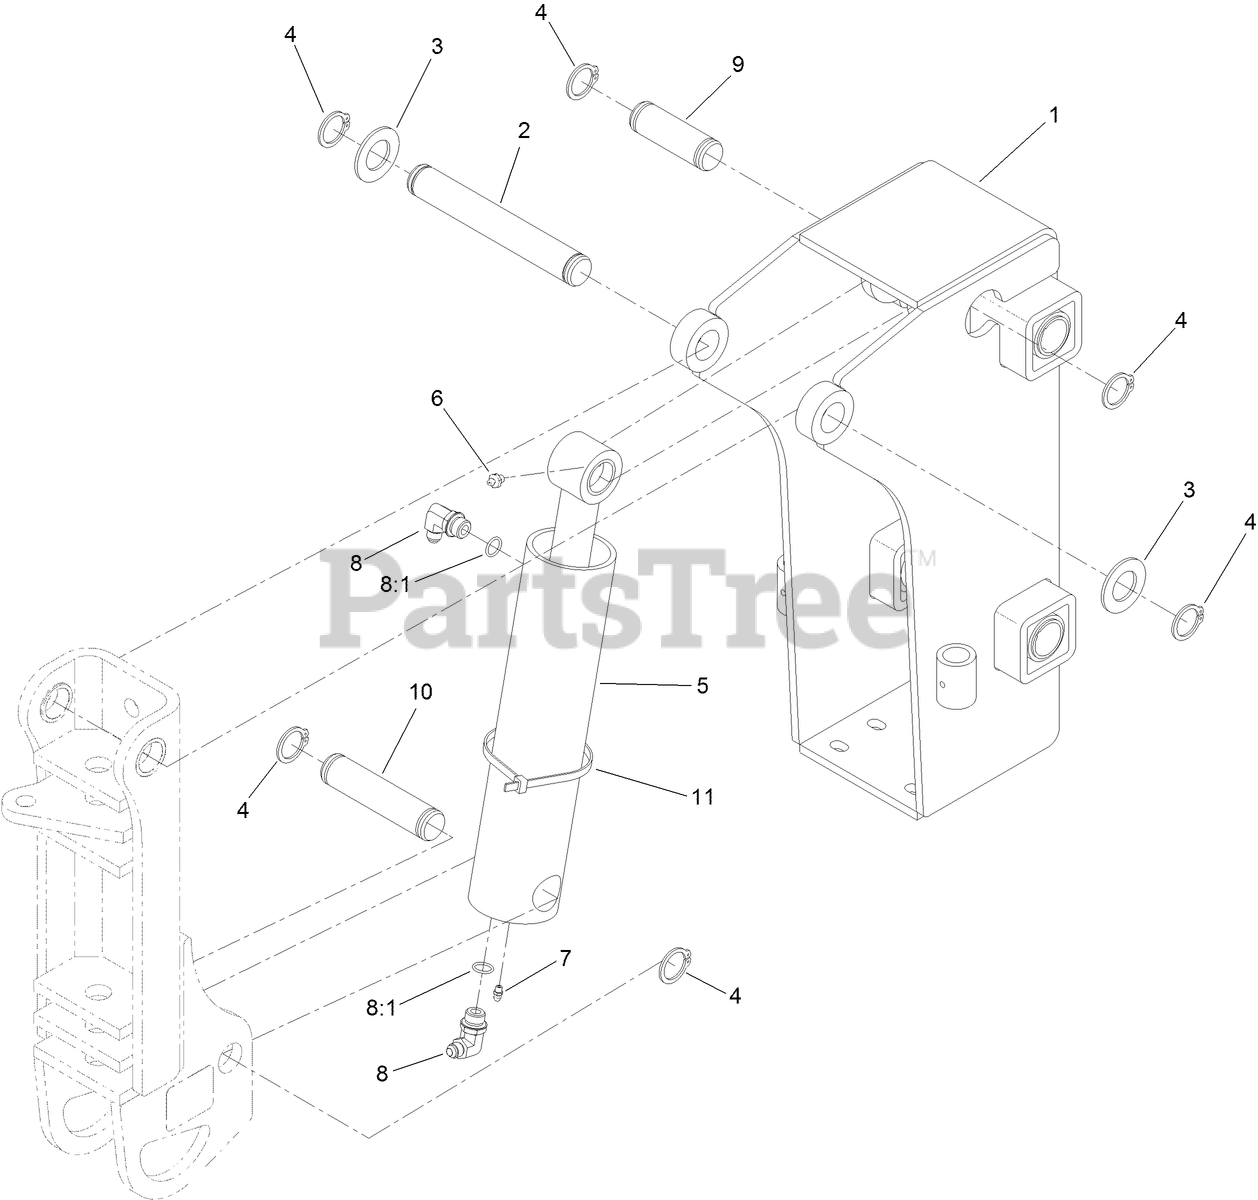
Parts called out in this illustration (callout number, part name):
1	FRAME-LIFT, PLOW
2	PIN-LIFT
3	WASHER-10 GAUGE
4	RING-RETAINING, EXTERNAL
5	HYD CYLINDER ASM
6	FITTING-GREASE
7	FITTING-GREASE
8	FITTING-ELBOW, 90 DEG
8:1	O-RING
9	PIN-CLEVIS
10	PIN-CLEVIS
11	TIE-CABLE
